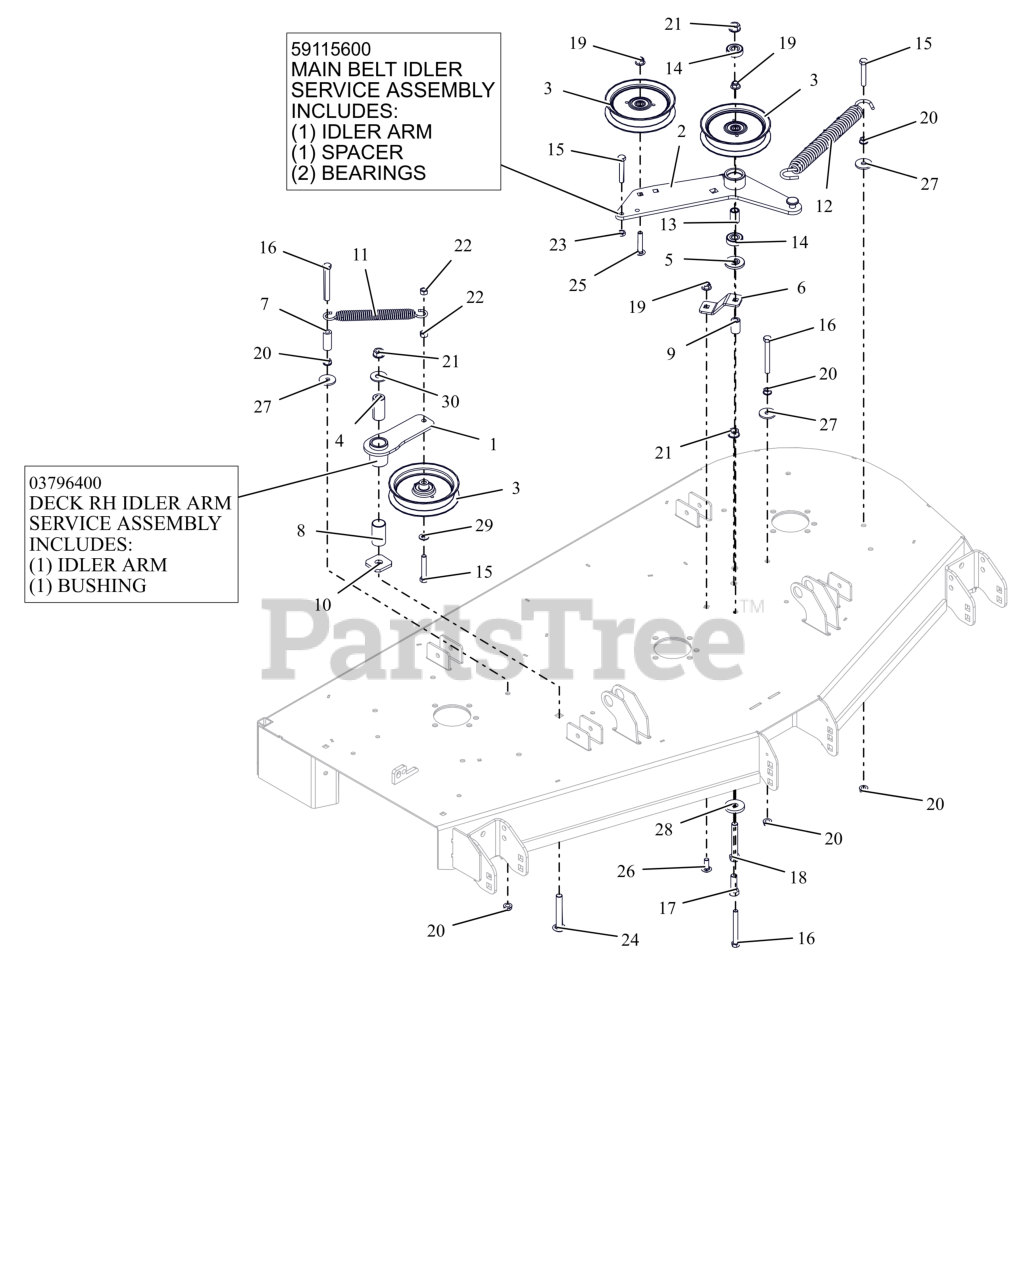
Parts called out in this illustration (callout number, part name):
1	WMT, IDLER ARM - BLACK
1	ASM, IDLER ARM (DECK)
2	WLDMT, DECK PTO IDLR ARM
2	ASSEMBLY, MAIN BELT IDLER
3	IDLER, FLAT 5.00"
4	BSHG, SPCR .502X.997X2.03 PM
5	SPACER, IDLER ARM
6	PTO FIXED IDLER MTG BRKT -RED
7	HOSE, .38 X 1.65
8	BSHG, 1.00X1.125X1.937
9	BUSHING, SLV .380X.750X1.190
10	WSHR-FLT .640X1.75X.250
11	SPRING, EXTENSION
12	SPRING, EXTENSION
13	SPACER .510 X .75 X 1.1485
14	BRG-BALL .500X1.38X.437
15	BLT,HEX .38-16X2.25 G5 ZCC
16	BLT, HEX .38-16X3.25 G5 ZCC
17	BLT,HEX .50-13X1.50 G5 ZCC
18	BLT,HEX .50-13X3.25 G5 ZCC
19	NUT,NYL-FLG .38-16 GF ZCC
20	NUT, SPNLK-FLG .38-16 G5 ZCC
21	NUT-LK-CTR-FLG .500-13 GG ZCC
22	NUT-LK-CTR .38-16 ZC120
23	NUT-JAM .375-16 G2 ZCC
24	BTL,RHSSN .500-13 X 3.25 G5 ZCC
25	BLT,RHSSN.375-16X2.00 G5 ZCC
26	BLT,RHSSN .38-16X1.00 G5 ZCC
27	WSHR,FLT .406X1.375X.135 ZCC
28	WSHR-FL-STL 0.557X1.625X0.25 ZCC
29	WSHR,FLT .406X.812X.065 ZCC
30	WSHR,FLT .563X1.375X.109 ZCC
